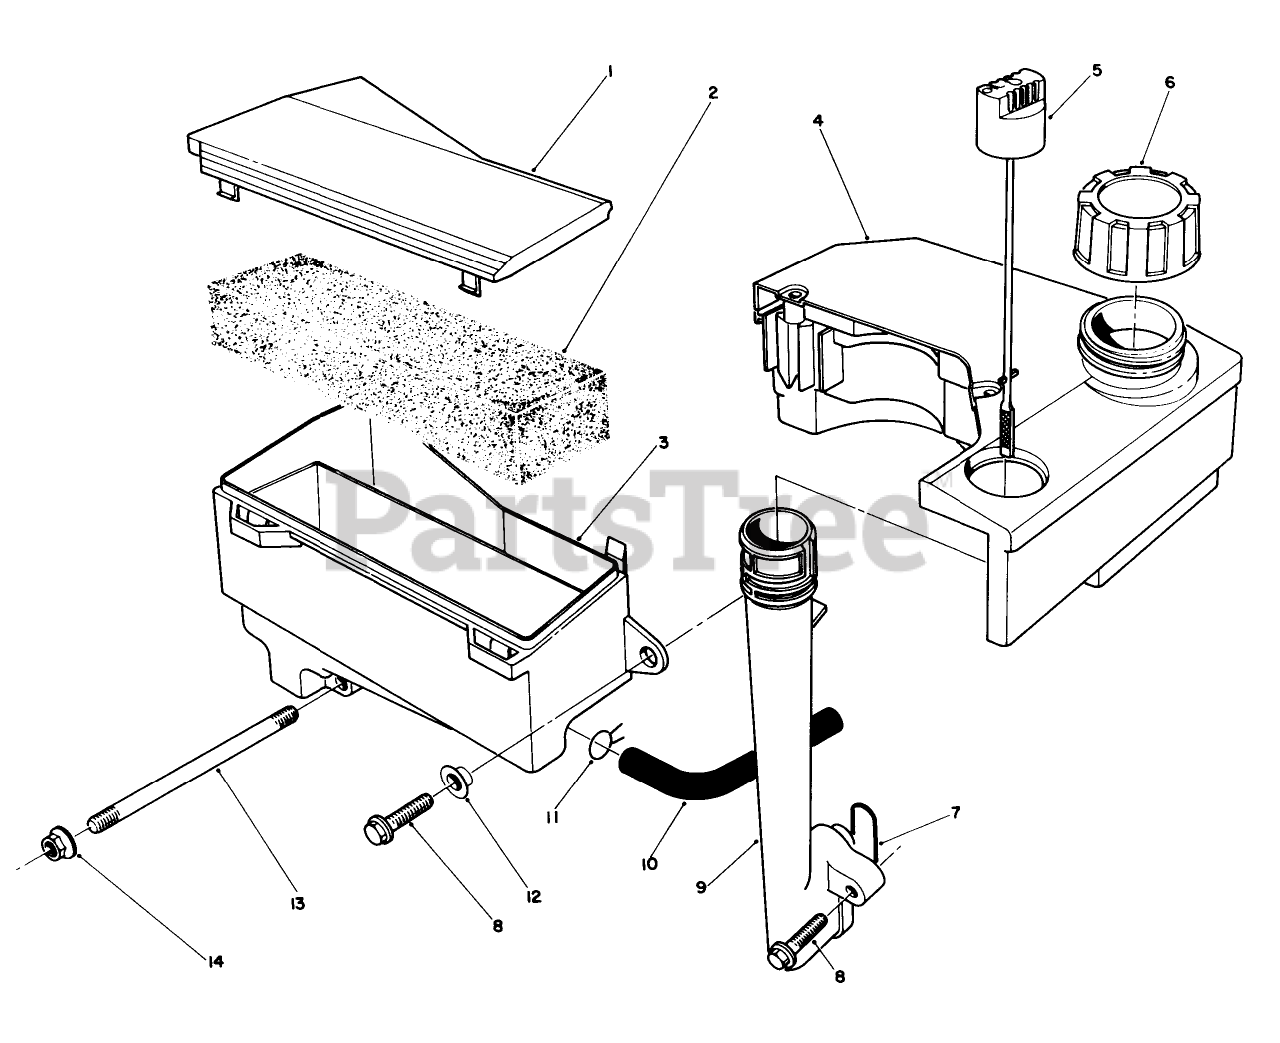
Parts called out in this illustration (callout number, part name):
1	AIR CLEANER CAP
3	AIR CLEANER
4	TANK ASM
6	GAS CAP ASM
7	O-RING
11	CLAMP F/W ENGINE
12	SPACER
